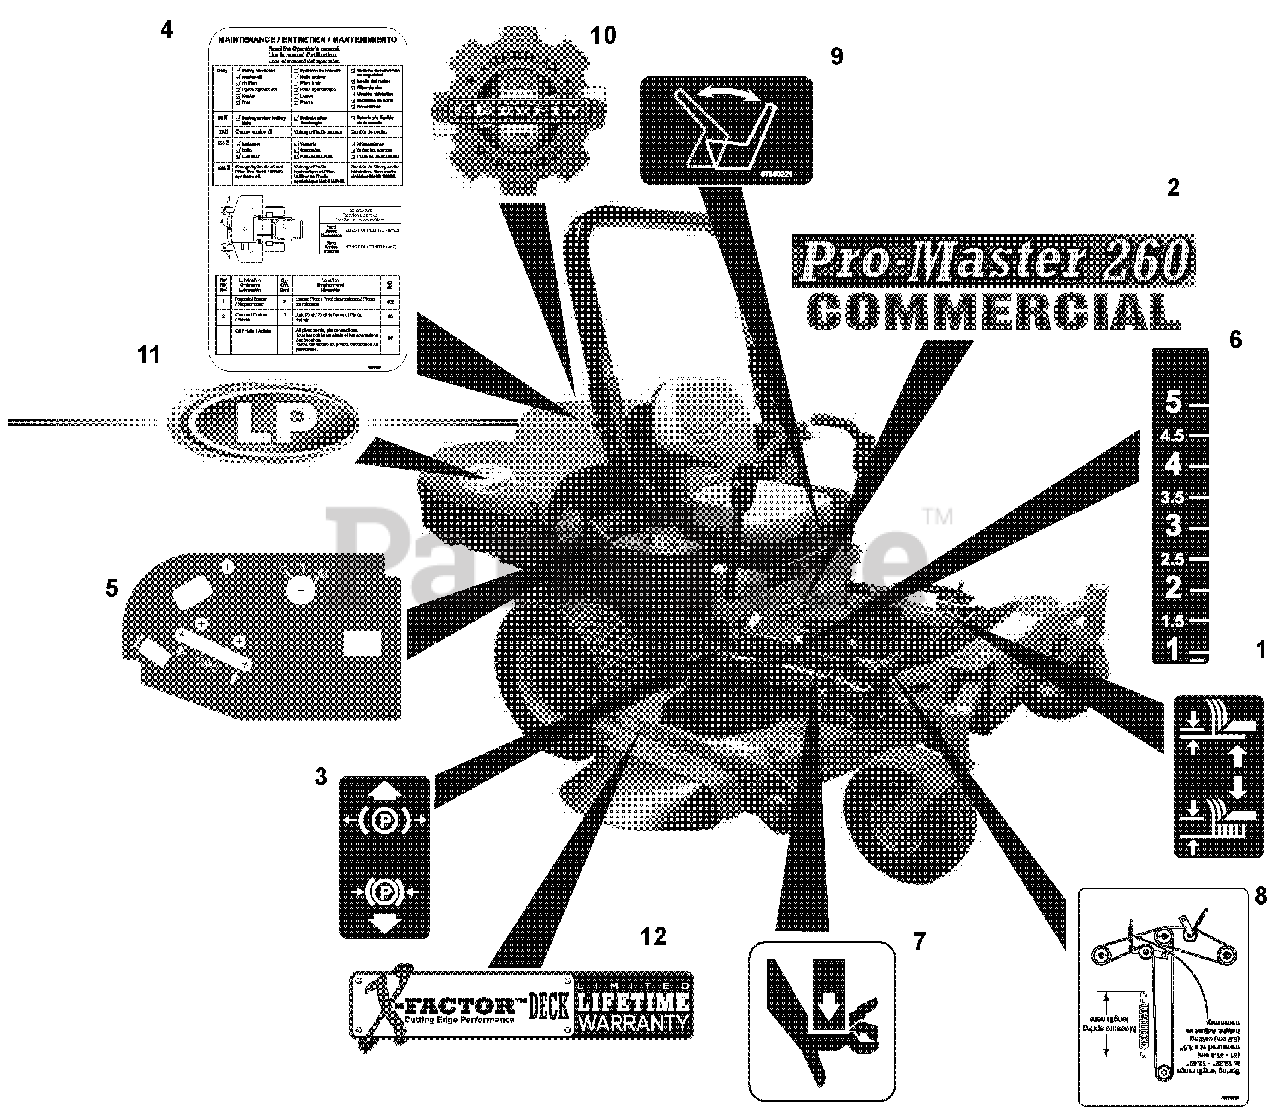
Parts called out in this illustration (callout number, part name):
1	Decal, Lift Lever
2	Decal, Pro-Master 260
3	Decal, Parking Brake Lever
4	Decal, Maintenance Instructions
5	Decal, Control Panel
6	Decal, Height of Cut
7	Decal, Pinch Point
8	Decal, Belt Routing
9	Decal, Seat Release
10	Decal, Gravely Heritage, Large
11	Decal, LPG Logo
12	Decal, X-Factor Deck
